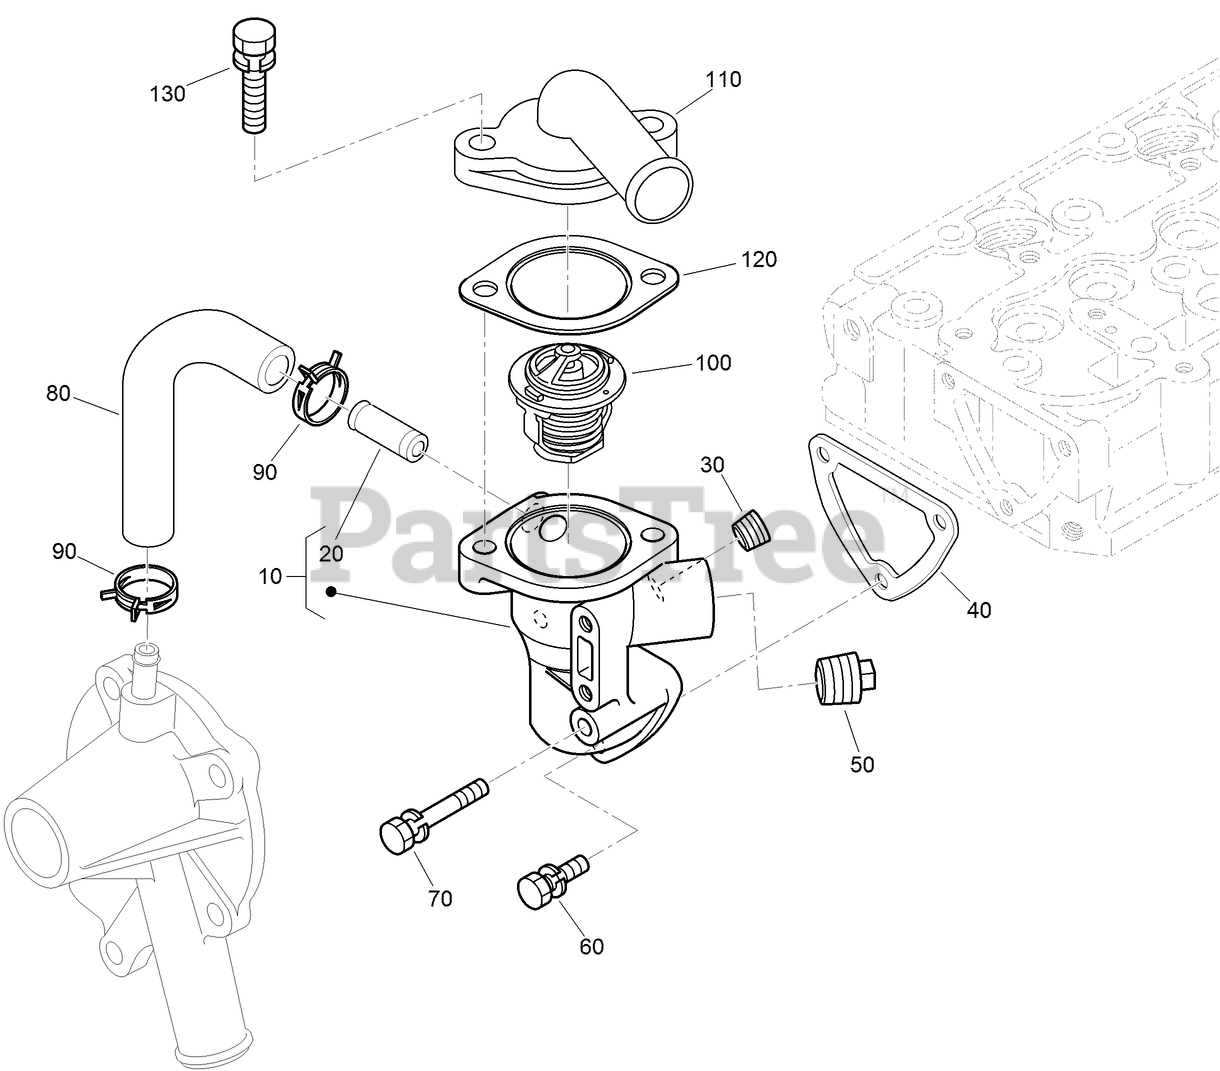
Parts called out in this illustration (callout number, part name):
10	WATER FLANGE ASM
20	PIPE-RETURN, WATER
40	GASKET-FLANGE, WATER
70	BOLT-SEMS
80	PIPE-RETURN, WATER
90	CLAMP-HOSE
100	THERMOSTAT ASM
110	COVER-THERMOSTAT
120	GASKET-THERMOSTAT
